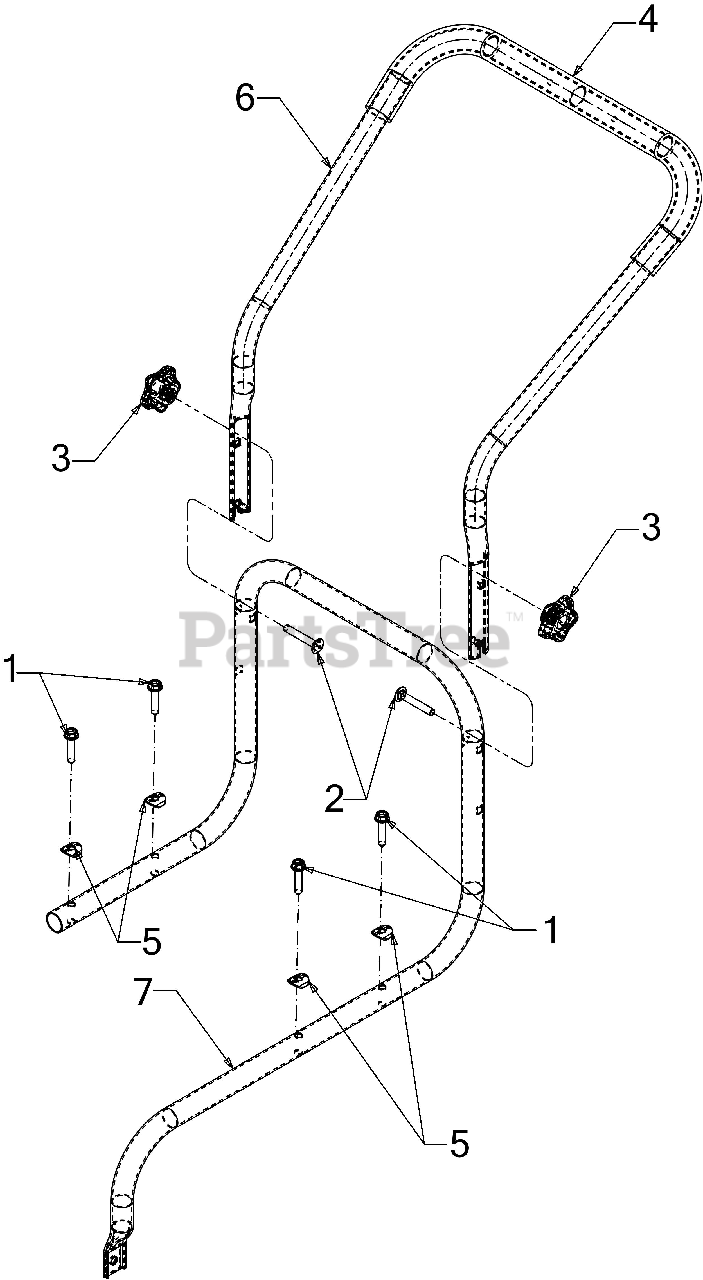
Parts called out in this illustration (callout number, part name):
1	HEX SCREW WASHER 5/16-18 x 1.5
2	BOLT 5/16-18 x 2.00 GR5
3	STAR KNOB 5/16-18
5	SADDLE WASHER
